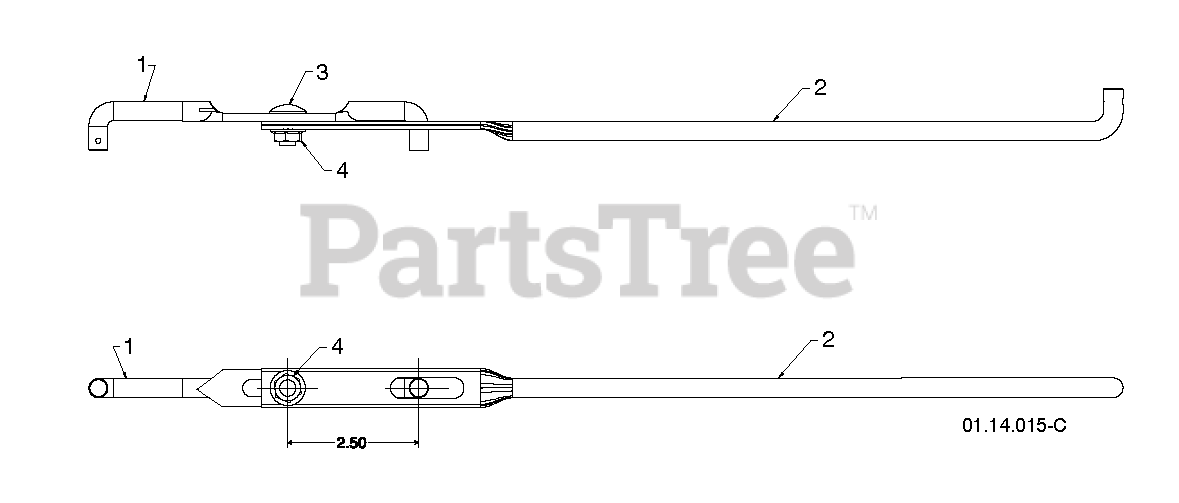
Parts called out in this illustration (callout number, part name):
1	ROD.SHIFTER.TOP.HYD
2	ROD, LOWER, SPEED CONTROL
3	BOLT
4	NUT.FLANGE.5/16
